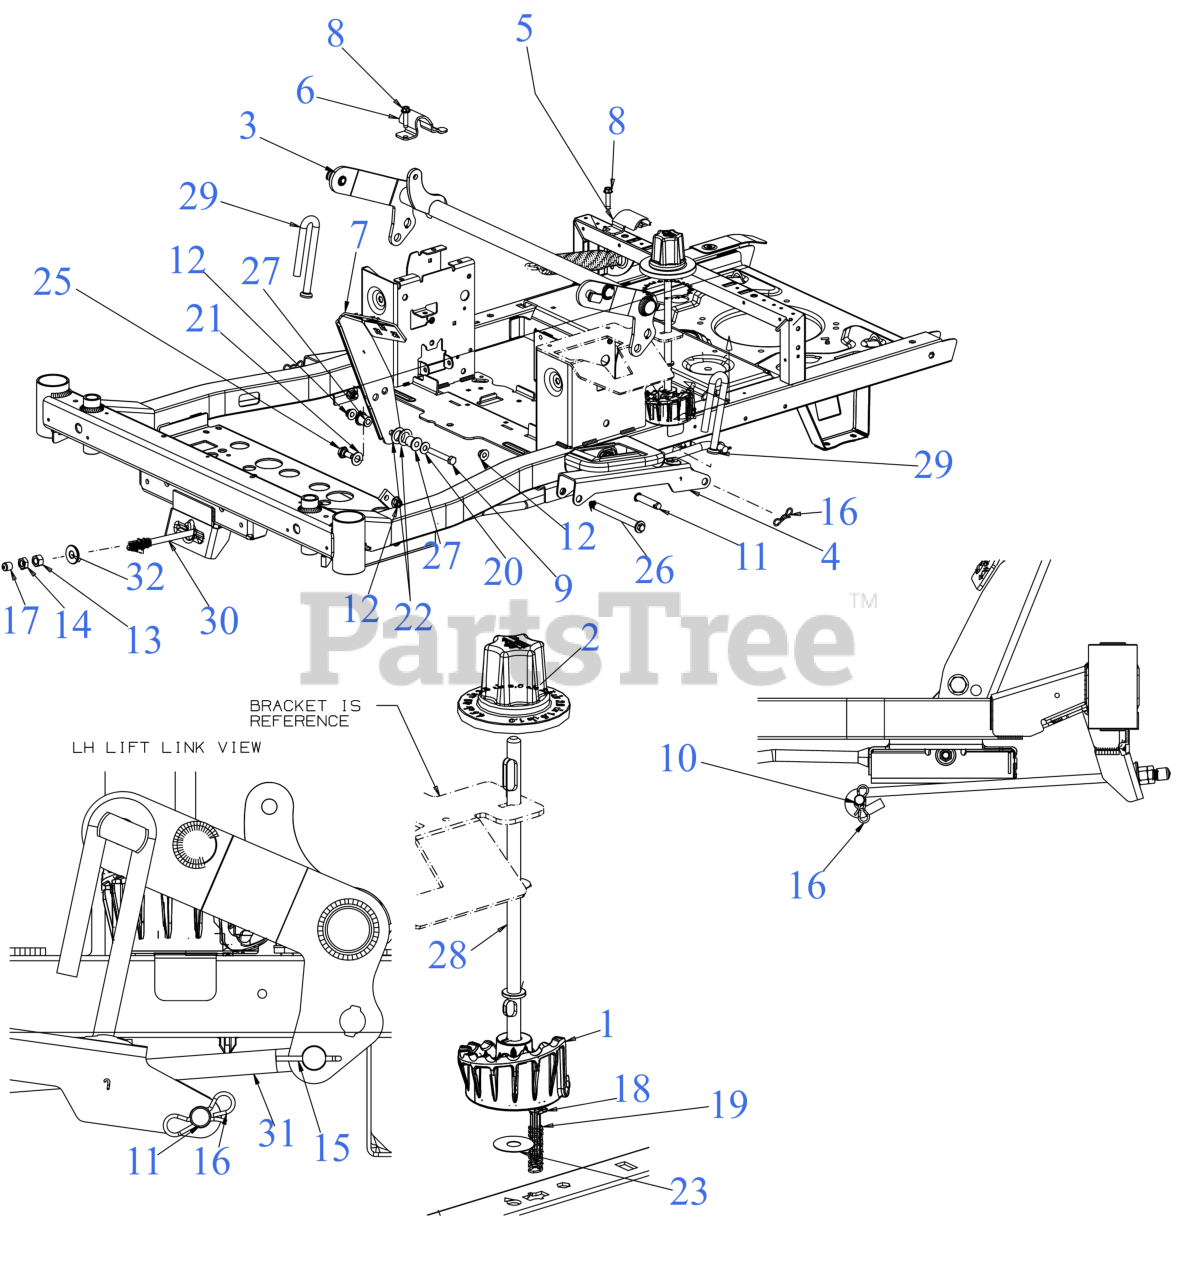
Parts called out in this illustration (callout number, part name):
1	DECK LIFT CUP
2	DECK HEIGHT ADJUSTMENT KNOB
3	LIFT SHAFT ASSEMBLY
4	DECK LIFT LINK
5	LIFT SHAFT (RETAINER) (LH)
6	LIFT SHAFT (RETAINER) (RH)
7	DECK LIFT PEDAL
8	SCREW 5/16-18 x 1.25
9	HEX SCREW-3/8-16X2.5 GR5
10	CLEVIS PIN .500 x 1.875
11	CLEVIS PIN .50 x 2.5
13	HEX NUT NYLOK 1/2-13
15	COTTER PIN
16	BOW TIE COTTER PIN
17	LIFT ROD END CAP
18	DETENT PLUNGER
19	COMPRESSION SPRING .531 OD 1.75 LG
20	FLAT WASHER
21	FLAT WASHER .510 x .995
22	FLAT WASHER .793ID x 1.24OD x .060
23	SHIM WASHER .50 x 1.5 x .02
25	SHOULDER SCREW
26	SHLDER SCREW .498x5.0 3/8-16
27	FLANGE BEARING (.38x.75x.77)
28	DECK HEIGHT ADJUSTMENT ROD
29	HANGER ROD
30	DECK LIFT ROD (FRONT)
31	LIFT PEDAL ROD
32	DECK LIFT PIVOT CUP
